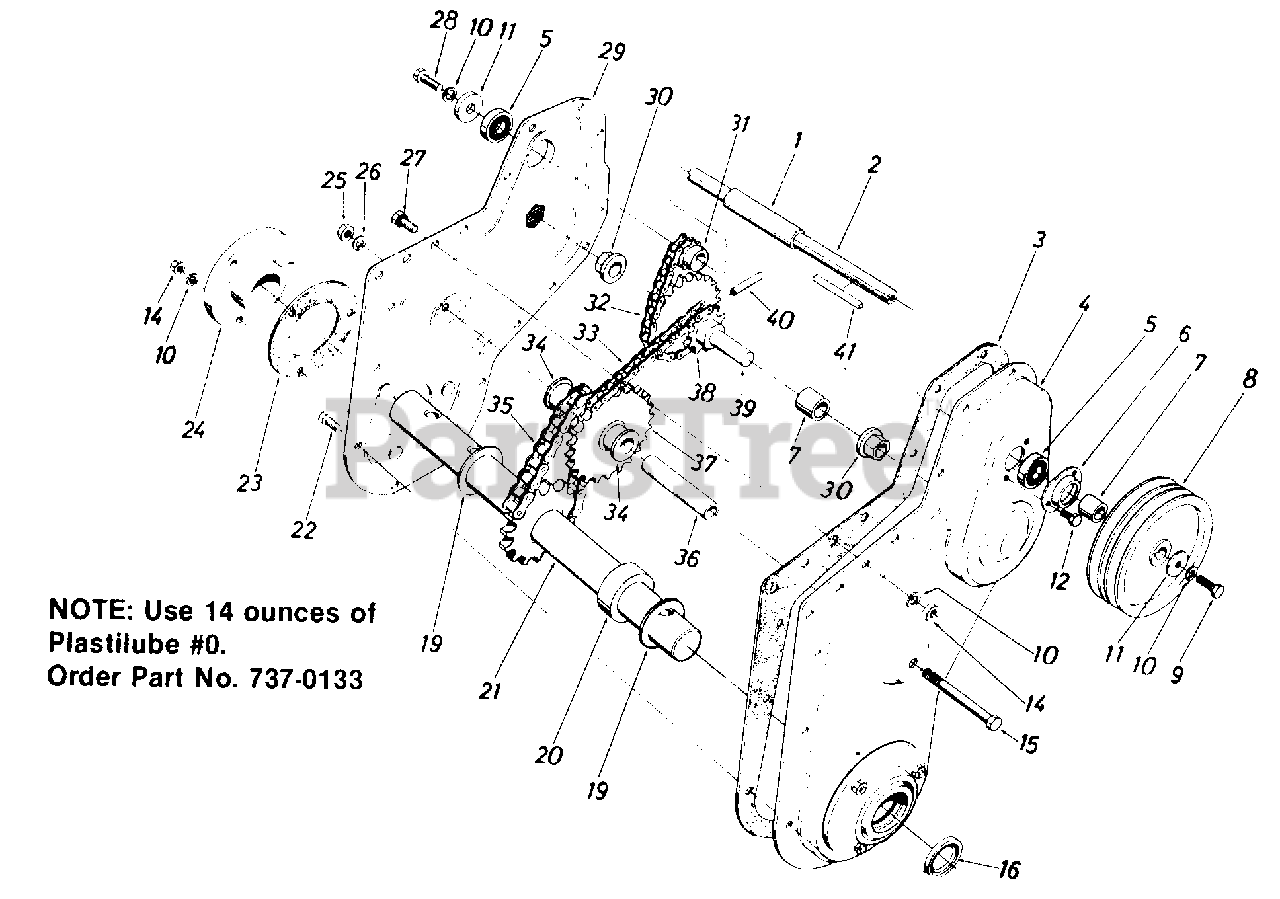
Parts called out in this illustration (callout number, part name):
1	Spacer .657 I.D. x .78 O.D. x 2.19
2	Jack Shaft
3	Gasket for Housing
4	Housing Half - L.H.
5	Ball Bearing .625 I.D. x 1.375 O.D.
6	Bearing Housing
7	Spacer .625 I.D. x .88 O.D. x 1.035
8	Chain Case Pulley 6.00" Dia.
9	Hex Bolt 5/16-18 x 1.00" Lg. Special
10	L-Wash. 5/16" Scr.
11	Fl-Wash. 5/16" I.D. x 1.125 O.D. x .125
12	Hex Self-Tap Scr. 1/4-20 x .50" Lg.
14	Hex Nut 5/16-18 Thd.
15	Hex Bolt 3/8-16 x 3.25" Lg.
16	Oil Seal 1" I.D. x 1.357 O.D.
19	Fl-Wash. 1.0" I.D. x 1.62 O.D. x .090
20	Spacer 1.0" I.D. x 2.0" O.D. x .68
21	Tine Shaft Ass'y.
22	Hex Self-Tap Scr. 1/4-20 x .50" Lg.
23	Gasket for Bearing Hsg.
24	Bearing Housing Ass'y.
25	Hex Nut 3/8-16 Thd.
26	L-Wash. 3/8" Scr.
27	Hex Sems Bolt 5/16-18 x 1.00" Lg.
28	Hex Bolt 5/16-18 x .62" Lg. Special
29	Housing Half - R.H.
30	Hex Flanged Bearing .630 I.D.
31	Sprocket 10 Teeth x .500 Pitch
32	#41 Chain 1/2" Pitch x 34 Links - Endless
33	#420 Chain 1/2" Pitch x 48 Links - Endless
34	Flange Bearing .626 I.D.
35	#50 Chain 5/8" Pitch x 28 Links - Endless
36	Sprocket Shaft
37	Sprocket Bearing Sleeve Ass'y.
38	Sprocket Sleeve Ass'y.
39	Sprocket Shaft
40	Spring Pin Spiral 1/4" Dia. x 1.5" Lg.
41	Sq. Key 3/16 x 1.50" Lg.
